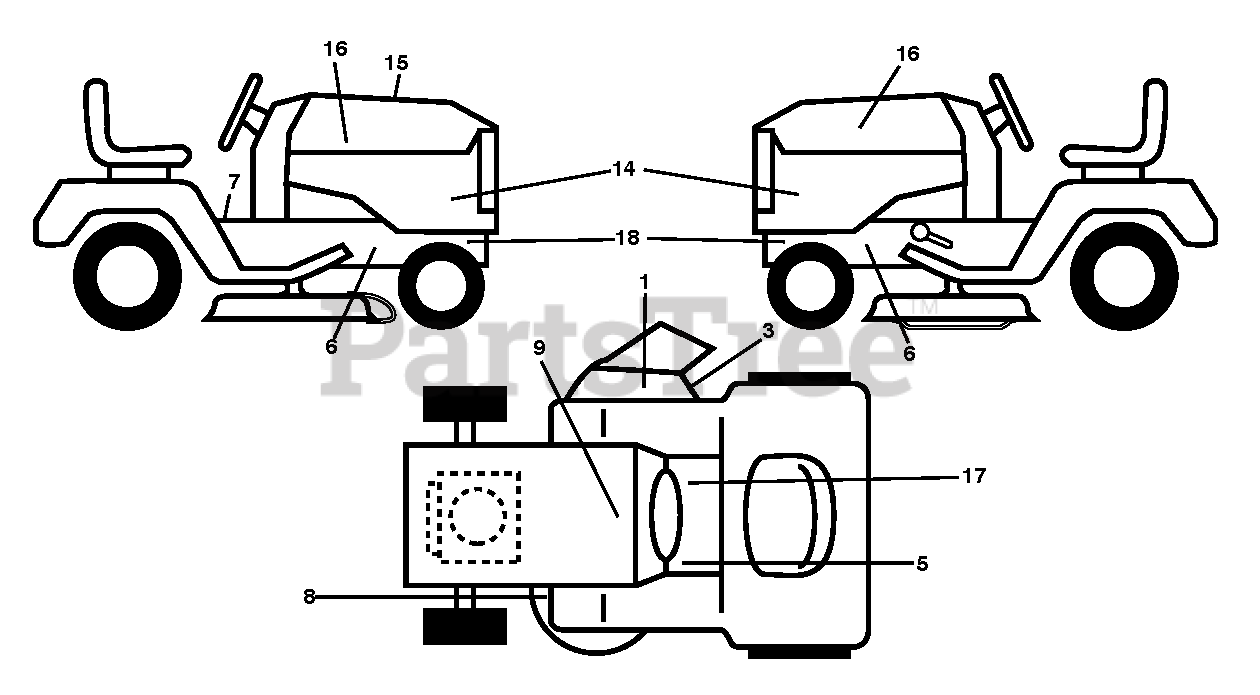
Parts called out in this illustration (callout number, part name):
1	DECAL, DECK DEFLECTOR, WARNING
3	DECAL.DFLCTR.WARNNG.CTFNGR.SYM
5	DECAL.FNDR.SDLE.BRAKE.CLUTCH.6
6	DECAL.WARNING.SERVCE/FIRE
7	DECAL.READ.OWN.MAN.SYMBOL.LT
8	DECAL.V-BELT.SCH.42/46"MEC/ELE
9	DECAL BTRY SYMBOLS
14	DECAL.SDPNL.HUSGT2.668.SET
16	DECAL.BADGE.170MM.TEXTLOGO.
17	DECAL.PARKING.BRAKE.SADDLE.LT
18	DECAL.CHASSIS.HOT.MUFFLER
